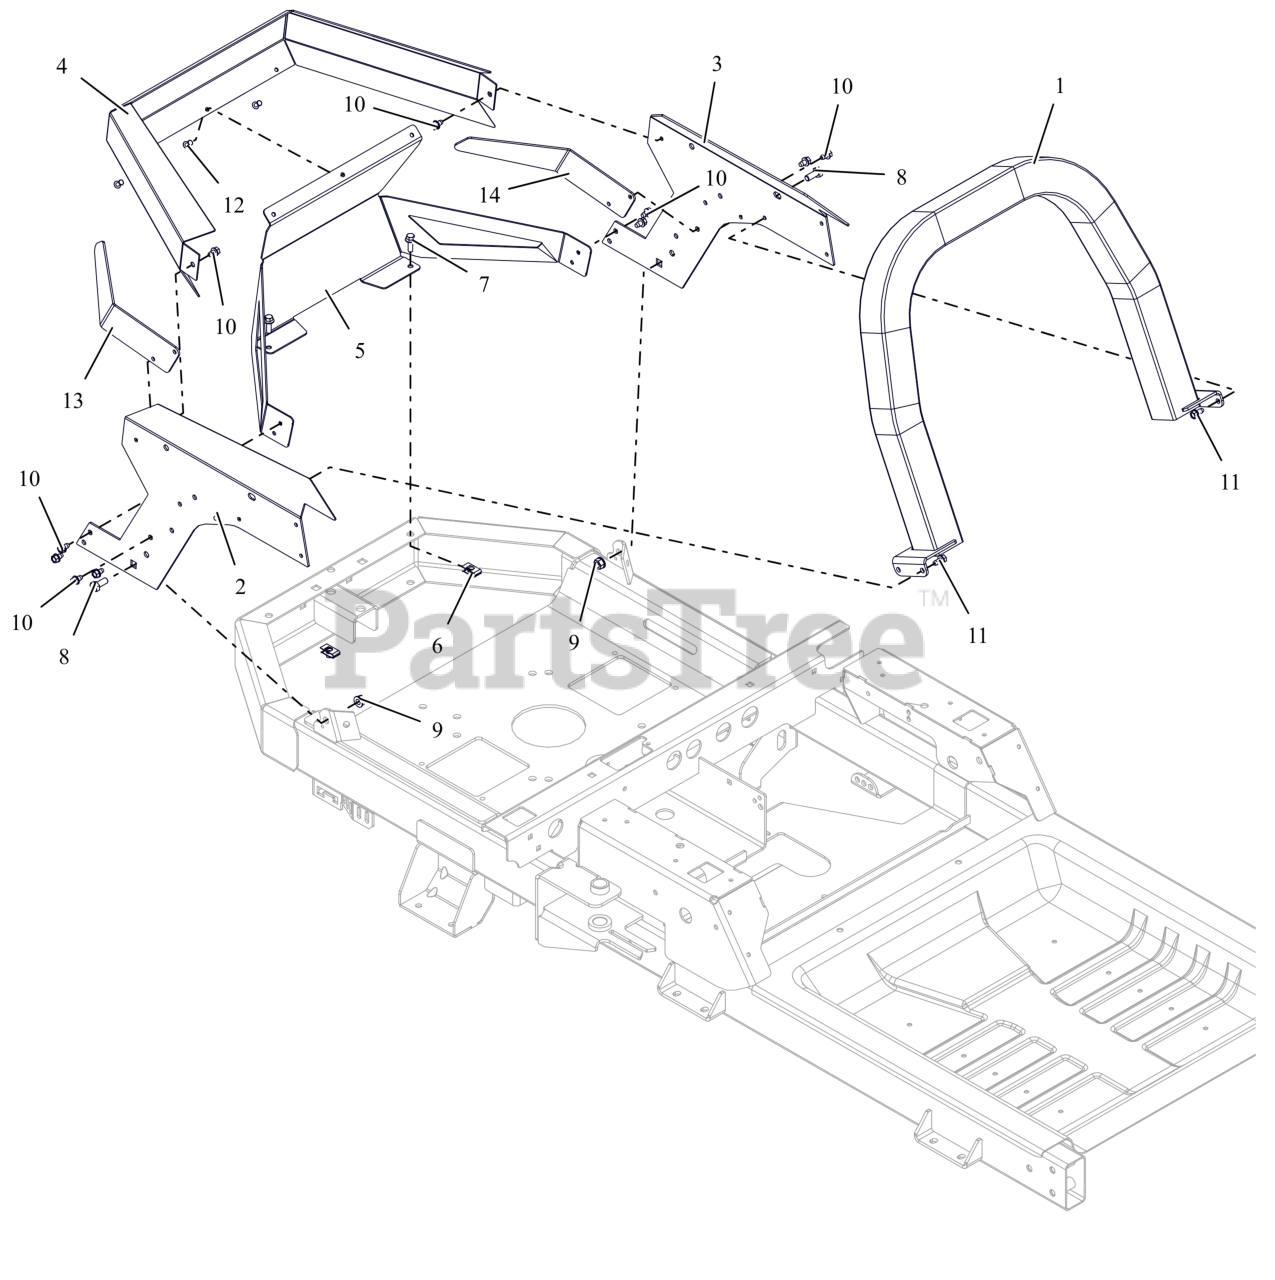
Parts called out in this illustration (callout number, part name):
1	ENGINE-TOP GUARD (ORANGE)
2	PANEL, RIGHT REAR FENDER MOUNT (ORANGE)
3	PANEL, LH REAR FENDER MOUNT (ORANGE)
4	GUARD, ENGINE WRAP (ORANGE)
5	GUARD, ENGINE -BOTTOM (BLACK)
6	NUT-RTNR .25-20X.56
7	BLT,HEX-FLG .25-20X.75 G5 BFP
8	BLT,HEX .31-18X.75 G5 ZCC
9	NUT-LK-TOP-FLG .312-18 GF ZCC
10	SCR,TAP .25-20X.375 HWH TR ZCC
11	SCR-TAP .25-20X.50 HWH ZCC
12	RIVET, #66 STEEL POP PD BLACK
13	SHIELD, RH, ENGINE GUARD VALVE
14	SHIELD, LH, ENGINE GUARD VALVE
